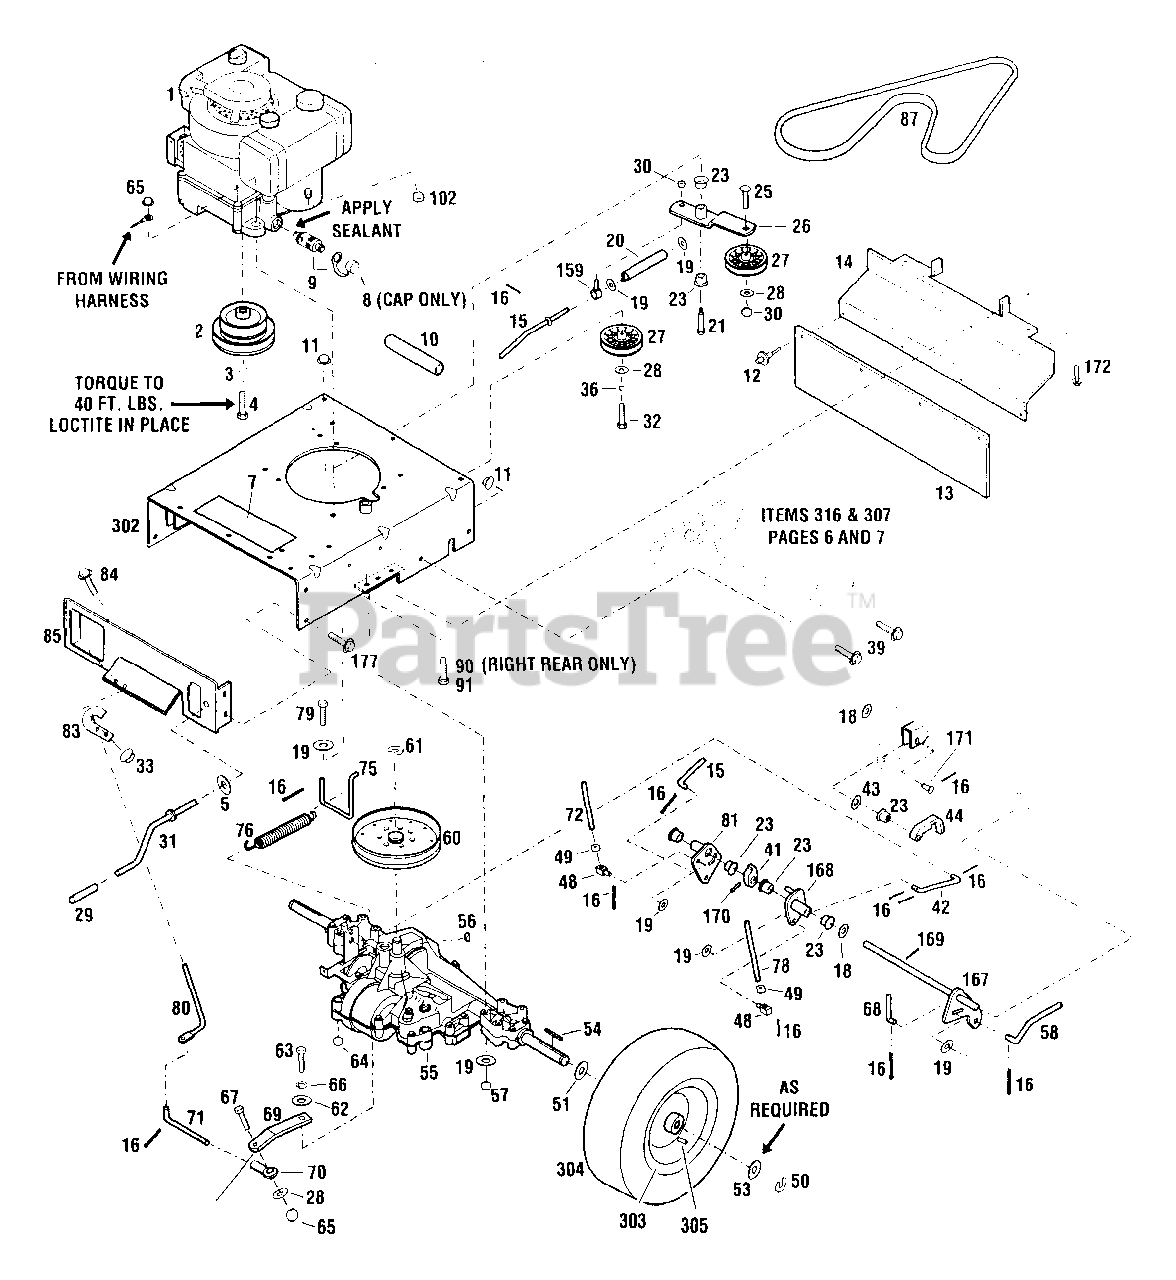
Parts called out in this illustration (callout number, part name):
1	Engine - Electric Start
1	Engine - Recoil Start
2	Engine Pulley
3	Lock Washer, 7/16
4	Bolt, 7/16-20 x 1-3/4
5	Washer, Nylon
7	Warning Decal
8	Oil Valve Cap
9	Oil Valve
10	Oil Drain Hose
11	Flange Locknut, 3/8-16
12	Pop Rivet, 3/16
14	Flap Bracket
15	Lower Transmission Rod
16	Cotter Pin, 3/32 x 5/8
18	Flat Washer, 1/2
19	Flat Washer, 5/16
20	Compression Spring
21	Shoulder Bolt
23	Nyliner, 1/2
25	Carriage Bolt, 3/8-16 x 1-3/4
26	Idler Arm
27	Idler Pulley
28	Flat Washer, 3/8
29	Plastic Grip
30	Top Locknut, 3/8-16
31	Lift Crank Assembly
32	Bolt, 3/8-16 x 1-3/4
33	Flange Locknut, 1/4-20
36	Lock Washer, 3/8
39	Flange Lock Screw, 3/8-16 x 1
41	Interlock Cam
42	Lower Brake Rod
43	Washer, Flat 1/2
44	Interlock Latch
48	Swivel Block
49	Jam Nut, 5/16-18
50	Retaining Ring
51	Flat Washer
53	Special Washer
54	Square Key, 3/16 x 2-1/2
55	Transmission Assembly
56	Woodruff Key, 3/16 x 3/4
57	Top Locknut, 5/16-18
58	Lower Blade Rod
60	Transaxle Pulley
61	Retaining Ring
62	Flat Washer, 1/4
63	Screw, 1/4-28 x 3/4
64	Flange Locknut, 5/16-18
65	Locknut, 3/8-16
66	Lock Washer, 1/4
67	Screw, 3/8 x 1-1/4
68	Upper Blade Rod
69	Transmission Arm
70	Ball Joint
71	Shift Link Rod
72	Upper Transmission Rod
75	Spring Attachment Rod
76	Extension Spring
78	Upper Brake Rod
79	Screw, 5/16-18 x 2-3/4
80	Shift Rod
81	Clutch Arm Pivot
83	Shift Rod Bracket
84	Flange Lock Screw, 1/4-20 x 1/2
85	Backplate
87	V-Belt
90	Thread Forming Screw, 3/8-16 x 1-1/2
91	Thread Forming Screw, 3/8-16 x 1
102	Hex Nut, 1/4 20
159	Eye Bolt
167	Pivot Shaft Assembly
168	Brake Arm
169	Cotter Pin
170	Drive Pin, 5/32 x 1
171	Clevis Pin, 1/2 x 1-1/4
172	Screw, 5/16-18 x 3/4
177	Flange Screw, 5/16-18 x 3/4
302	Frame Weldment Ass'y
303	Wheel Rim
305	Valve Stem
